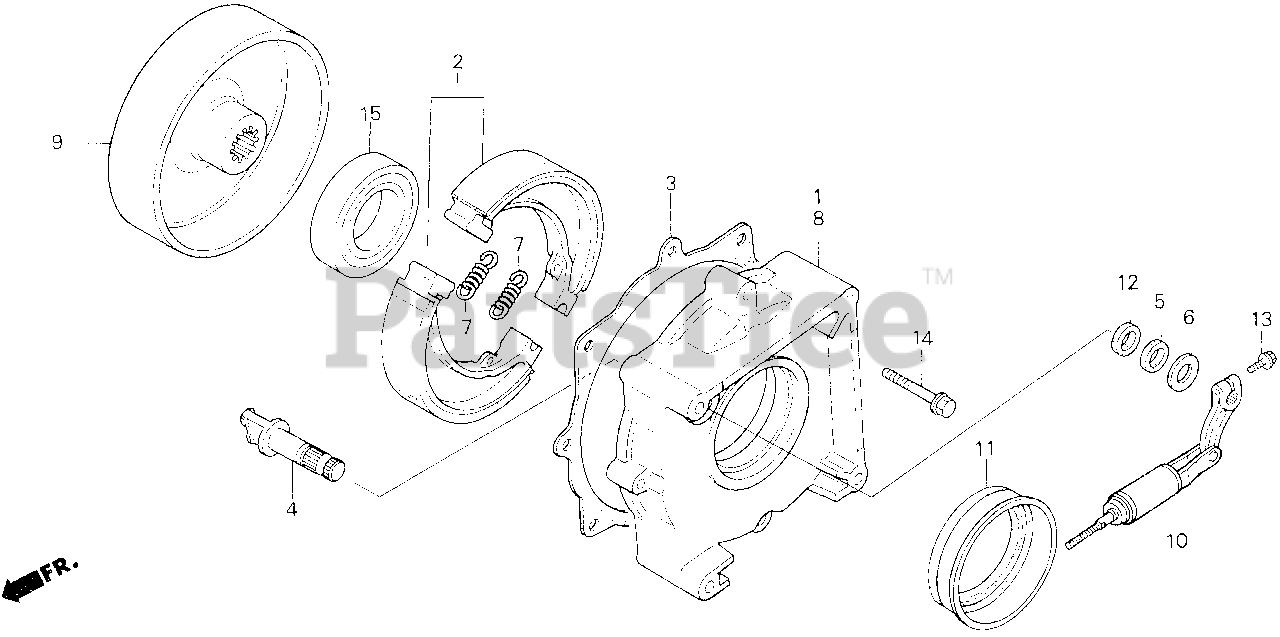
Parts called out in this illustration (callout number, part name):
1	PANEL, R. BRAKE
2	SHOE KIT, BRAKE
3	GASKET, BRAKE PANEL
4	CAM, BRAKE
5	DUST SEAL, BRAKE CAM
6	WASHER, BRAKE CAM
7	SPRING, RR. BRAKE SHOE
8	PANEL, L. BRAKE
9	DRUM, BRAKE
10	ARM, BRAKE
11	DUST SEAL (37X58X9)
12	DUST SEAL (17X23X3)
13	BOLT, FLANGE (8X25)
14	BOLT, FLANGE (8X40)
15	BEARING, RADIAL BALL (6007)
